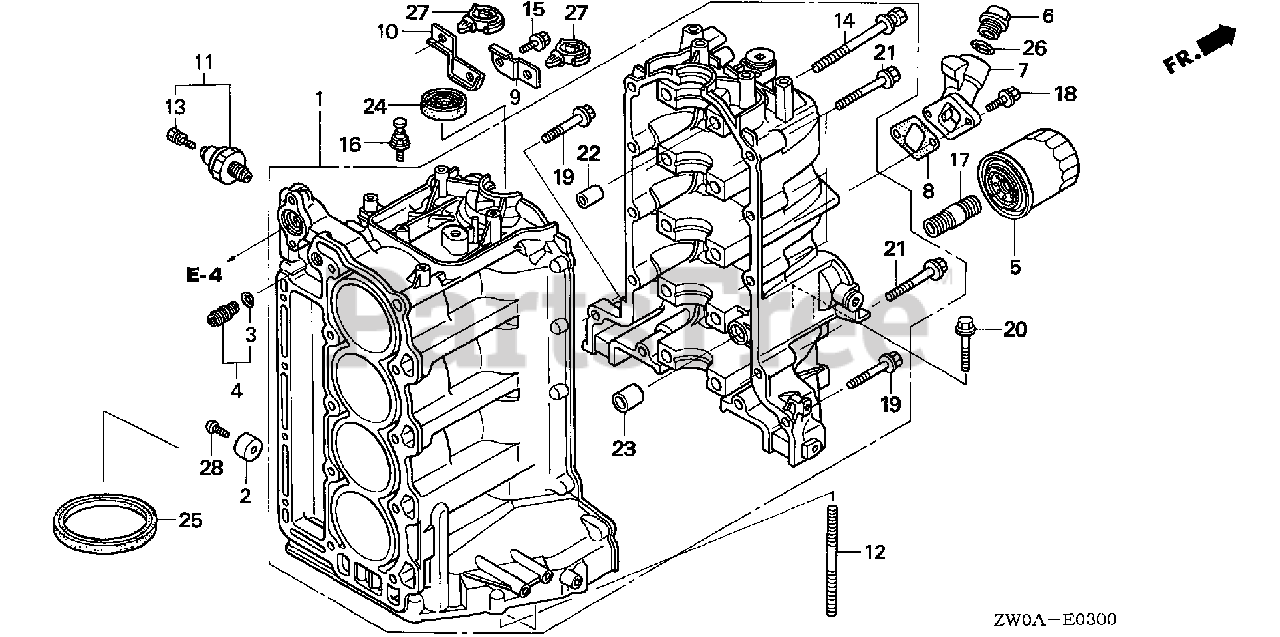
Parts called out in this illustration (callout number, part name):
1	BLOCK ASSY., CYLINDER *NH8* (DARK GRAY)
2	METAL, ANODE
3	O-RING (10.8X2.4) (ARAI)
4	ORIFICE ASSY., OIL PASSAGE
5	FILTER, OIL (FILTECH TOYO ROKI) (SOLD INDIVIDUALLY)
5	FILTER, OIL (TOYO ROKI) (SOLD INDIVIDUALLY)
6	CAP, OIL (YELLOW)
7	EXTENSION, OIL FILLER *NH8* (DARK GRAY)
8	GASKET, EXTENSION OIL FILLER (NON-ASBESTOS)
9	BRACKET, HARNESS CLIP
10	CLAMP C, ENGINE WIRE HARNESS
11	SWITCH, OIL PRESSURE
12	BOLT, STUD (10X125)
13	SCREW-WASHER (4X8)
14	BOLT-WASHER (10X112)
15	BOLT, FLANGE (6X14) (CT200)
16	BOLT, TIMING BELT ADJUSTING SPRING
17	HOLDER, OIL FILTER
18	BOLT, FLANGE (6X22)
19	BOLT, FLANGE (8X35)
20	BOLT, FLANGE (8X40)
21	BOLT, FLANGE (8X50)
22	PIN, DOWEL (12X18)
23	PIN, DOWEL (18X22)
24	OIL SEAL (38X50X8)
25	OIL SEAL (98X80X10) (NOK)
26	O-RING (26X2.7)
27	CLIP, WIRE HARNESS (BLACK)
28	SCREW, PAN (6X18)
